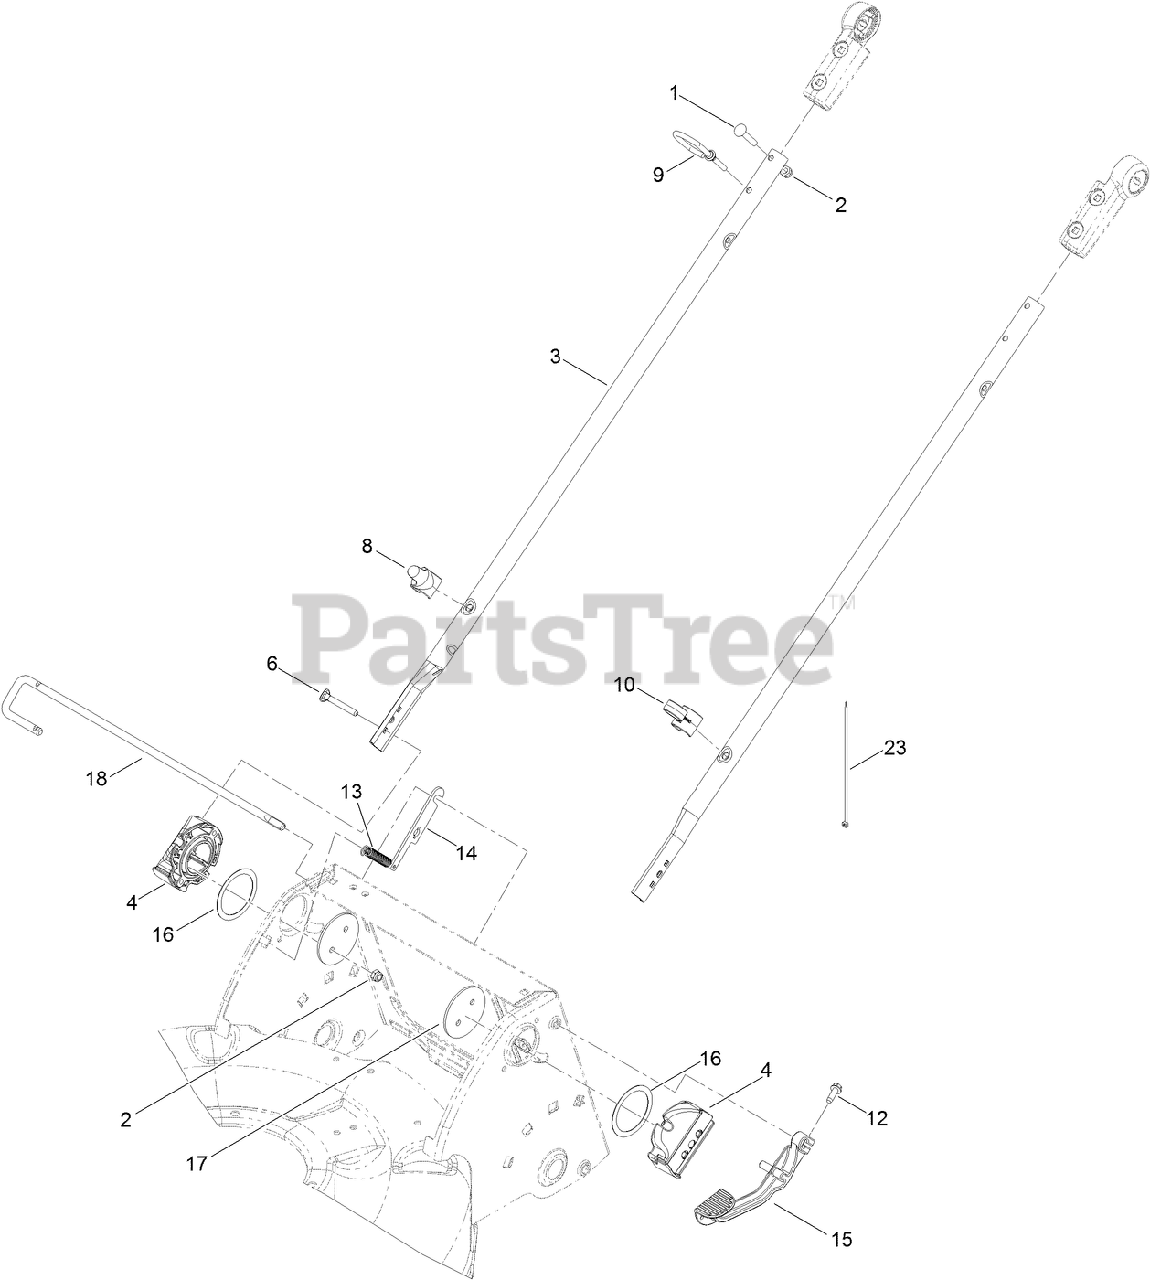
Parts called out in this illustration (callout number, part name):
1	SCREW-CARR
2	NUT-LOCK, NI
3	TUBE-LOWER
4	MOUNT-HANDLE
6	SCREW
8	GUIDE-ROPE, LOWER
9	GUIDE-ROPE, UPPER
10	GUIDE-CABLE
12	SCREW-HWHTF
13	SPRING-EXTENSION
14	PLATE-ROD, RELEASE
15	LEVER-RELEASE
16	WASHER-NYLON
18	ROD-RELEASE, HANDLE
23	TIE-CABLE
